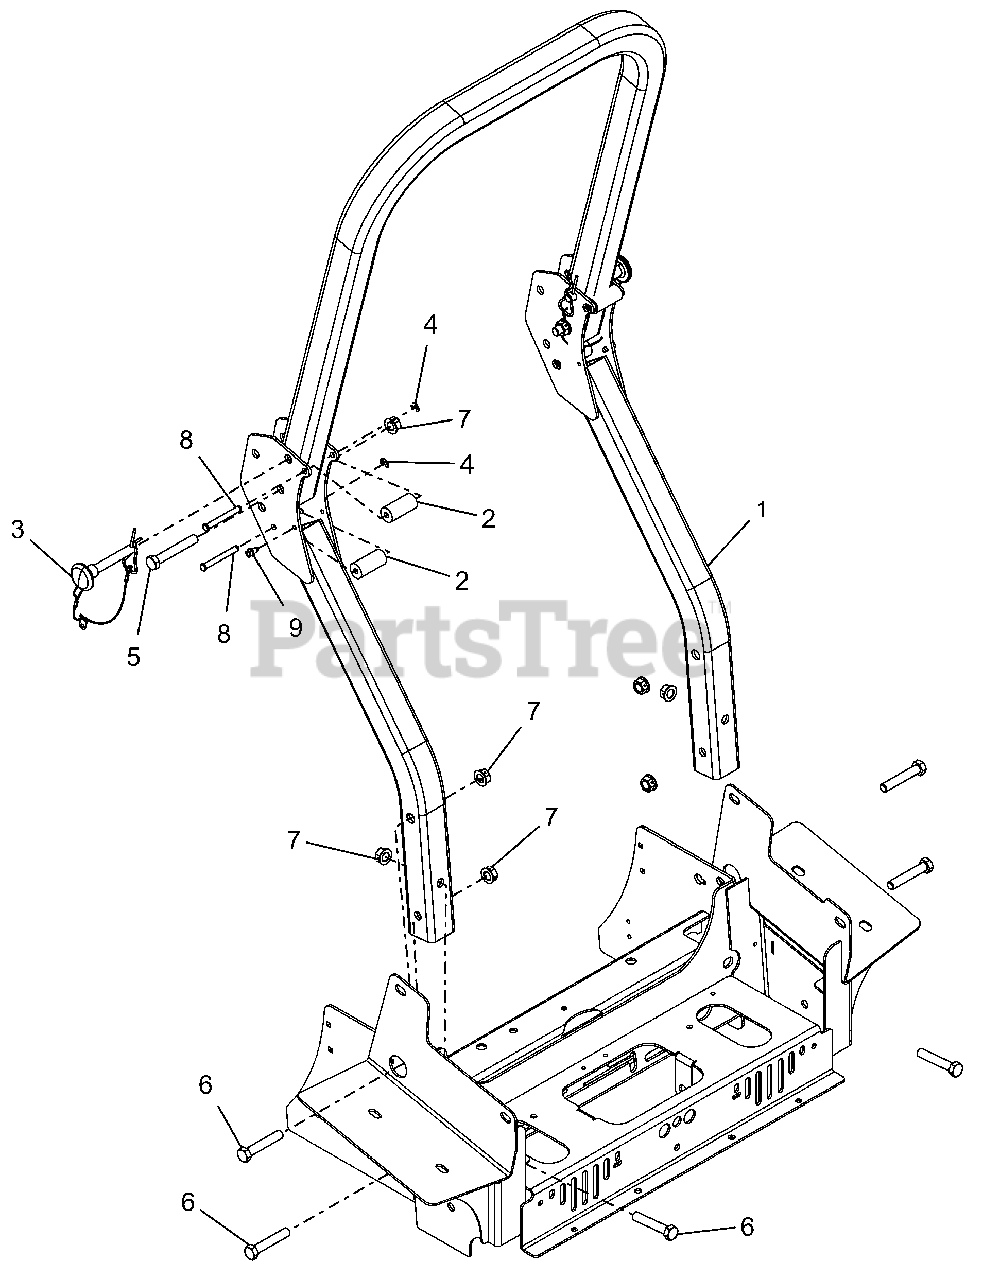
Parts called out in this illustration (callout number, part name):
1	ROPS, PT200/400 REPLACEMENT
2	BUMPER, ROPS ANTI-VIBRATION
3	PIN, ROPS W/LANYARD
4	RING, RETAINING-E .312 X .025
5	@BLT-HEX .50-13X3.25 GR5 YWZC
6	@BLT-HEX .50-13X2.75 GR5 YWZC
7	NUT-LK-CTR-FLG .50-13 YWZC
8	PIN, 5/16 X 2-9/16 WITH GROOVE
9	SCR-TAP .25-20X.50 HWH TR YWZ
